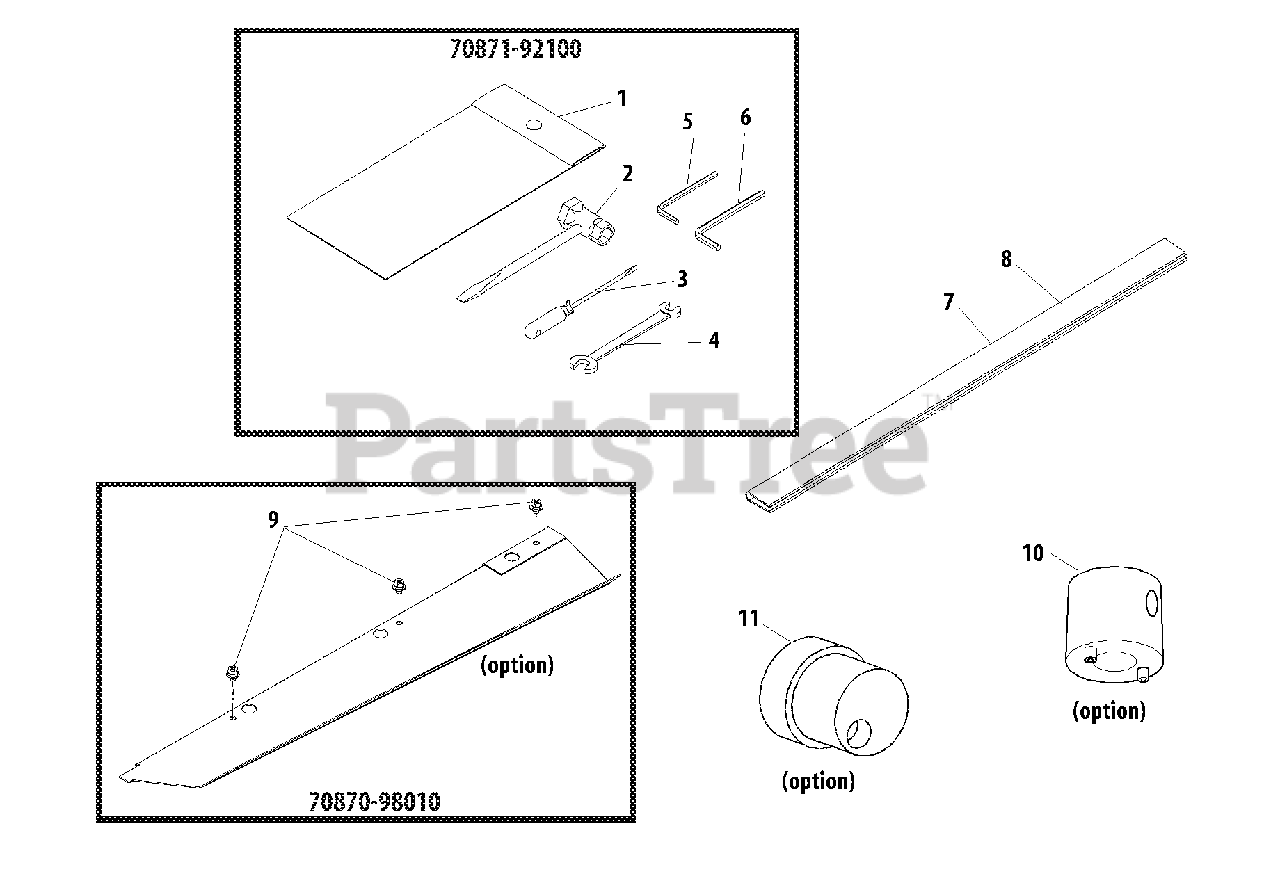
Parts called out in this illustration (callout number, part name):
1	BAG, TOOL
2	T-WRENCH
3	SCREWDRIVER
4	SPANNER - 8X10mm
5	HEX KEY - 4mm
6	HEX KEY - 6mm
7	COVER, BLADE - 30" (76cm)
8	COVER, BLADE - 40" (102cm)
9	BOLT - 5X8
10	CLUTCH DRUM WRENCH
11	HOLDER, BEARING
70870-98010	DEBRIS DEFLECTOR ASSY
70871-92100	TOOL KIT
